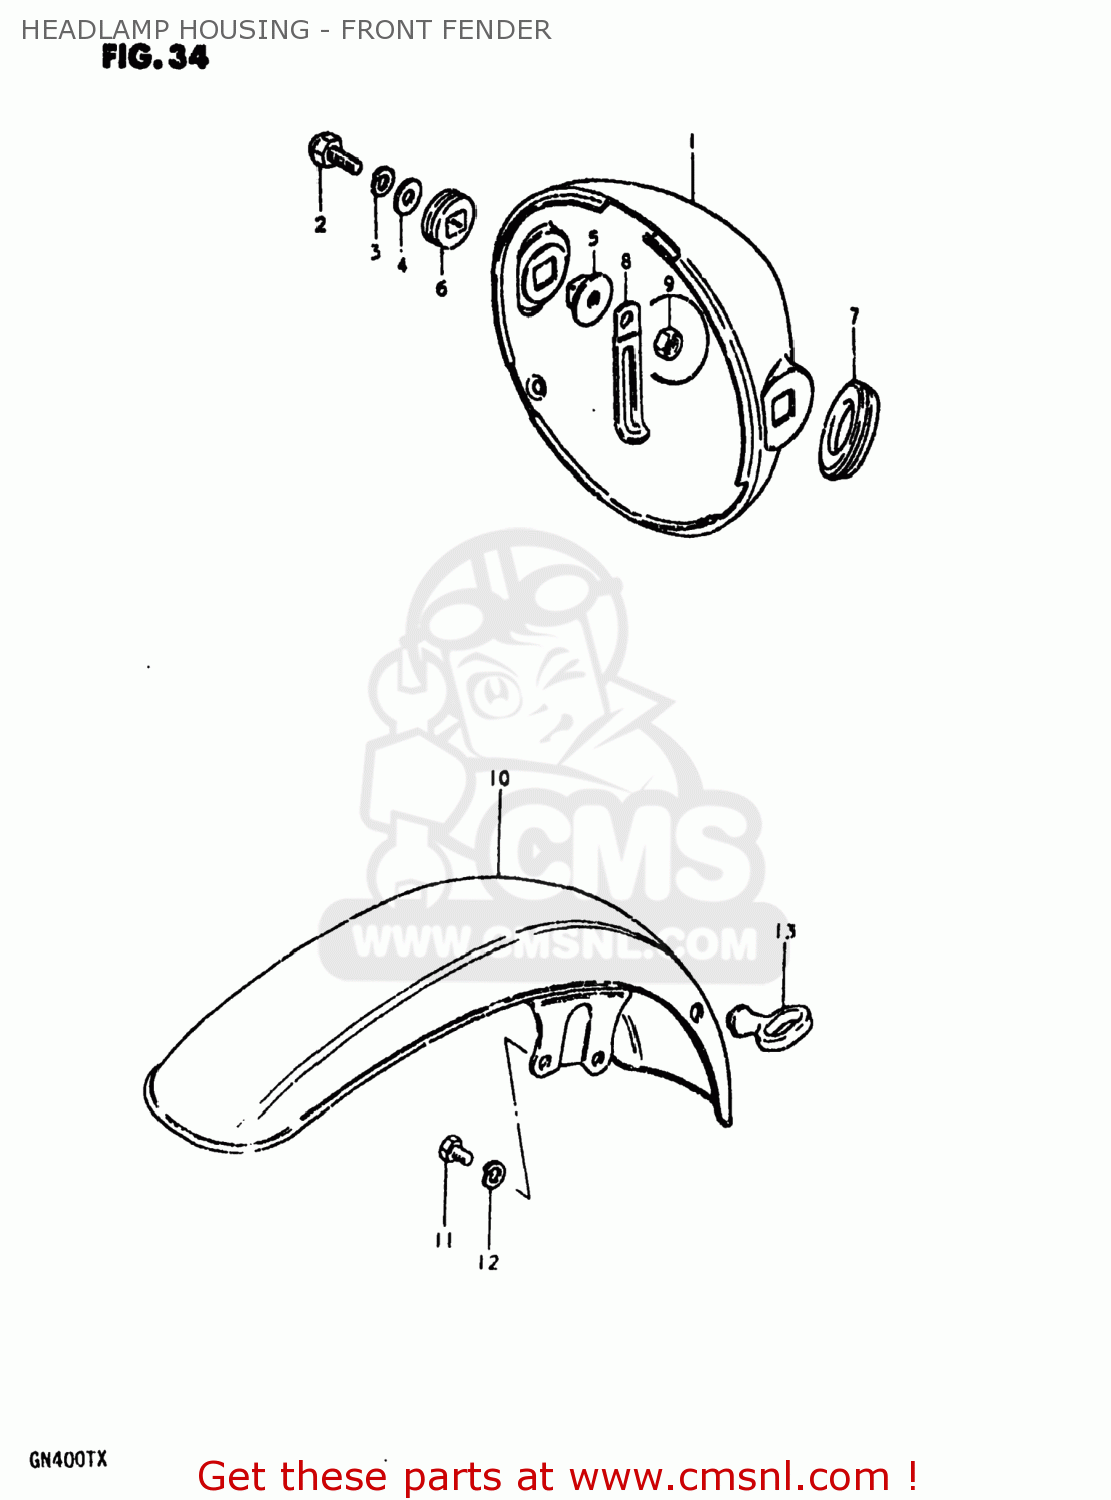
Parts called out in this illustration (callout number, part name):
1	HOUSING,HEADLAMP
2	BOLT
3	LOCK WASHER
4	WASHER
5	SPACER,HEADLAMP HOUSING
6	CUSHION,HEADLAMP HOUSING
7	GROMMET,HEADLAMP HOUSING
8	CLAMP
9	NUT 8MM
10	FENDER,FRONT
11	BOLT
12	LOCK WASHER
13	GUIDE,CABLE
